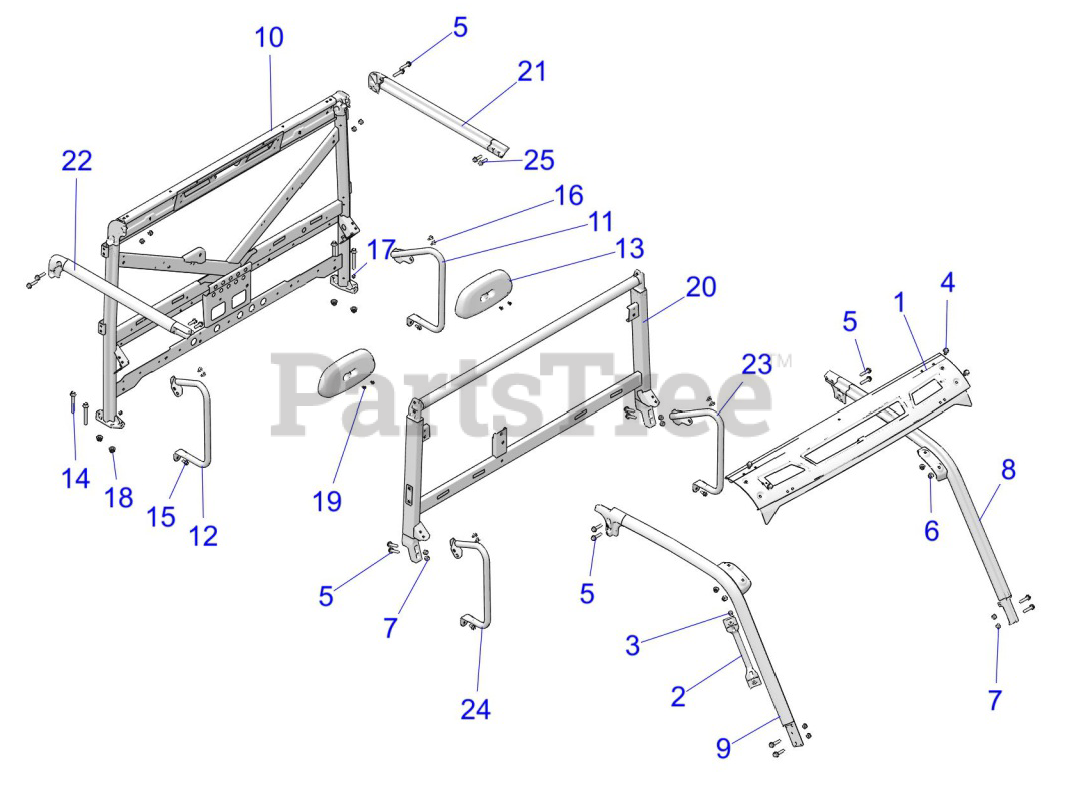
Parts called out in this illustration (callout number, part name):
1	K-PLATE,WSHLD MNT,UPR,ARN,CRW
2	HANDLE-GRAB-ROPS-BLK
3	BOLT-M8X1.25X20-HXFLG-TAP/R-OD
4	SCR-HXFL-M10X1.5X20 10.9 RIE P
5	SCR-HXFL-M10X1.5X45 10.9 RIE
6	NUT-HXFL-M10X1.5 8 ZB3 NYL
7	NUT-HEX-M10X1.5 10 ZB3 NYL
8	WELD-CAB FRAME-FRT-LH BLK
9	WELD-CAB FRAME-FRT-RH BLK
10	WELD-CAB FRAME- REAR-M.BLK
11	WELD-BOLSTER,LH, M.BLK
12	WELD-BOLSTER,RH, M.BLK
13	HEADREST-BLK
14	SCR-HXFL-M12X1.75X90 10.9 ZPC
15	SCR-HXFL-M8X1.25X20 8.8 ZOD P3
16	SCR-TXTH-M6X1.0X25 RIE
17	NUT-HEX-M8X1.25 10 P&O
18	NUT-HXFL M12X1.75 NYLOC ZOD
19	RIVET(50)
20	WELD-CAB FRAME, CTR, M. BLK
21	WELD-CAB FRAME-REAR-LH-BLK
22	WELD-CAB FRAME-REAR-RH-BLK
23	WELD-BOLSTER,FRONT,LH,M.BLK
24	WELD-BOLSTER,FRONT,RH,M.BLK
25	SCR-M10X1.50X35 HX/FL-Y/D
